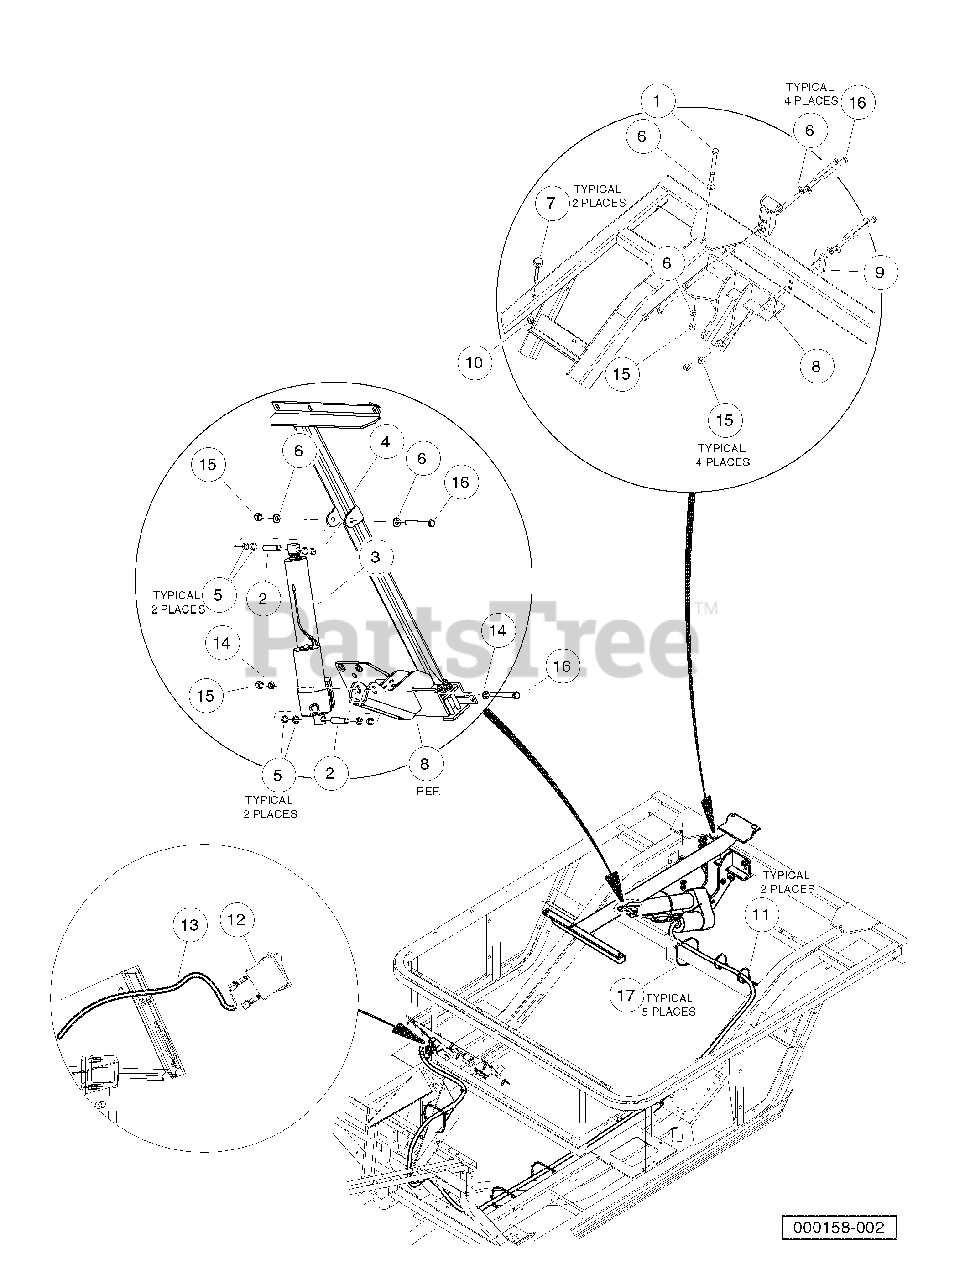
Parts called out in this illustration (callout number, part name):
1	Bolt, 3/8-16 X 425 Hex Head
2	Bushing Long
3	Actuator Assembly, Electric
4	Asm, Actuator Adapter
5	Body Spacer
6	Washer, 3/8 Type B Hard Flat
7	Bumper, Bed, Mtg, Front
8	Weldment, Bracket, Actuator
9	Plate, Back
10	Lock Nut, Flg M8 X 1.25 Nylon
11	Tie Wrap, 8.00" With Mount
12	Switch, Rocker, Spring Return, Bed Lift
13	Harness, AWD Bedlift
14	Washer, Lock, Hel Sp 3/8 Reg
15	Locknut, 3/8-16 Hex
16	Screw, 3/8-16 X 3.375 Hex Cap
17	Tie Wrap, 8" Nylon
